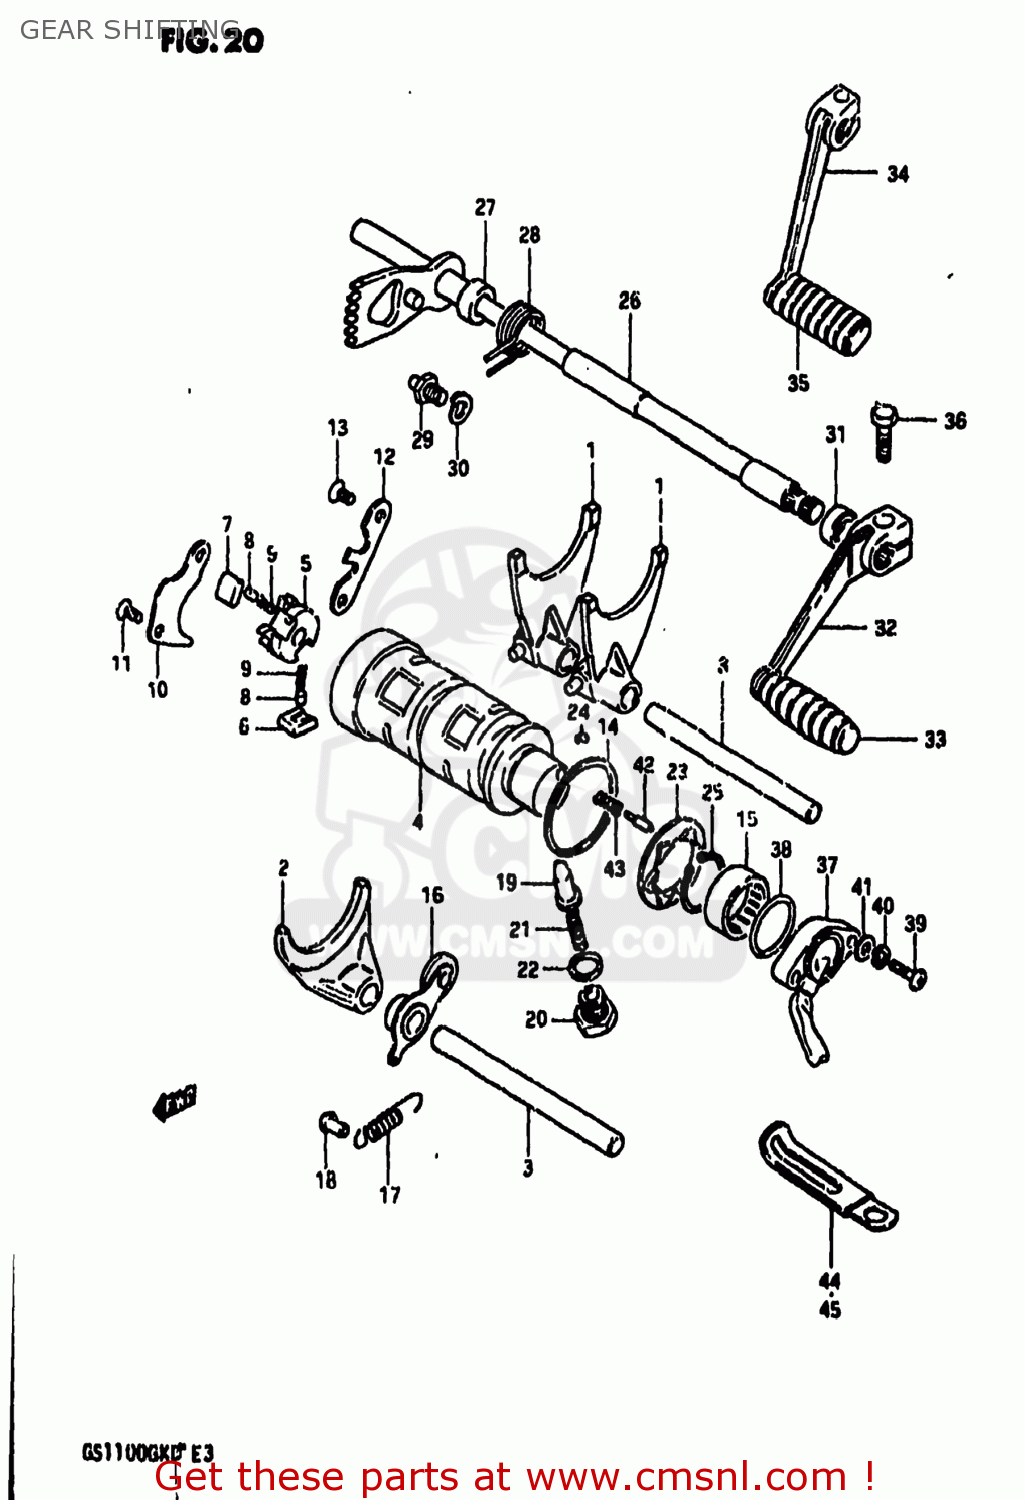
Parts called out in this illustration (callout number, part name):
1	FORK,GEAR SHIFT NO.1
2	FORK,GEAR SHIFT NO.3
3	SHAFT,GEAR SHIFT FORK
4	CAM,GEAR SHIFT
5	RETAINER,GEAR SHIFT CAM
6	PAWL,GEAR SHIFT NO.1
7	PAWL,GEAR SHIFT NO.2
8	PIN(5X8)
9	SPRING
10	LIFTER,GEAR SHIFT PAWL
11	SCREW
12	GUIDE,GEAR SHIFT CAM
13	SCREW
14	WASHER(40X45X1)
15	BEARING
16	STOPPER,GEAR SHIFTING
17	SPRING
18	RIVET
19	STOPPER,GEAR SHIFT CAM NO.2
20	HOLDER,GEAR SHIFT CAM STOP SPR
21	SPRING
22	GASKET(14X19.2X2) (NAS)
23	PLATE,GEAR SHIFT CAM STOPPER
24	PIN 4X6
25	CIRCLIP,25MM
26	SHAFT,GEAR SHIFT
27	SPACER (12X20X12)
28	SPRING
29	STOPPER,GEAR SHIFT CAM
30	WASHER
31	OIL SEAL
32	LEVER ASSEMBLY,GEAR SHIFTING
33	RUBBER,GEAR SHIFT PEDAL
34	LEVER ASSEMBLY,GEAR SHIFTING
35	RUBBER,PEDAL
36	BOLT
37	TERMINAL BASE ASSY,GEAR SHIFT
38	O-RING (D:2.4 ID:26.2)
39	SCREW 5X20
40	LOCK WASHER
41	WASHER
42	PIN(5X15.5)
43	SPRING
44	CLAMP L:35
45	CLAMP
